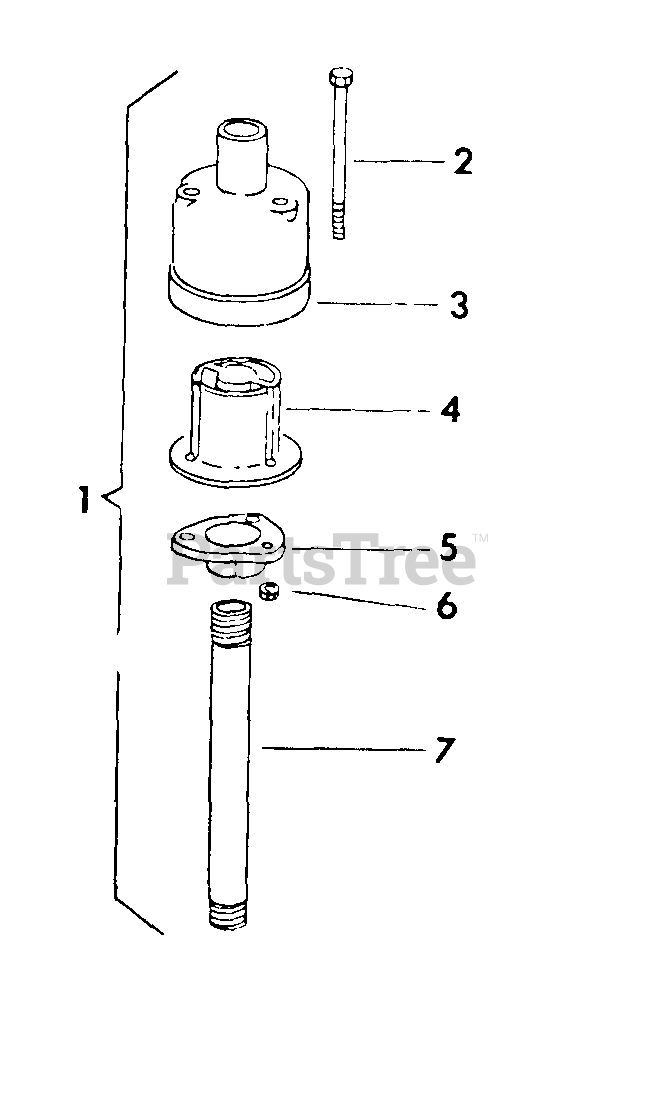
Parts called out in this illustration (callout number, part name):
1	SERVICE PARTS FOR SPARK ARRESTER
2	SCREW, 3/8-24 X 4-1/2 HEX-HD CAP
3	TOP, SPARK ARRESTER
4	BODY, SPARK ARRESTER
5	BASE, SPARK ARRESTER
6	NUT, SPARK ARRESTER BASE
7	PIPE, EXHAUST
